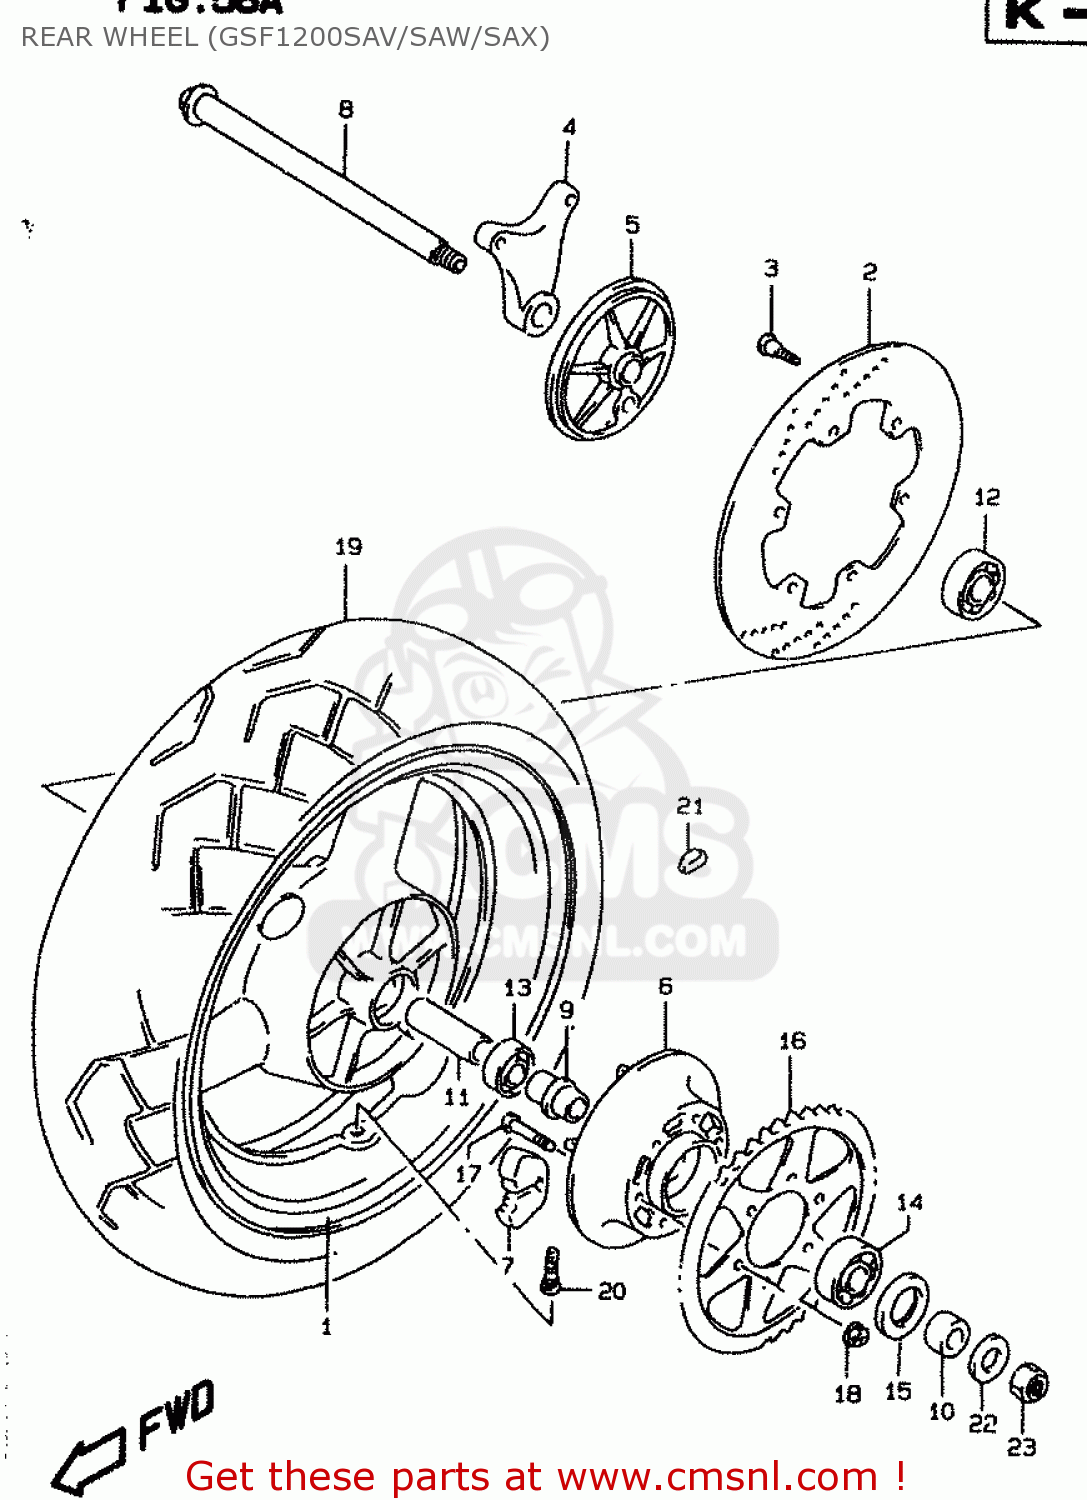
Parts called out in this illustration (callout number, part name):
1	WHEEL SET,REAR (17XMT5)
2	DISC,RR BRAKE
3	BOLT 8X33
4	BRACKET,RR CALIPER
5	PANEL,SPEED SENSOR RR
6	DRUM,RR SPROCKET
7	ABSORBER,RR HUB SHOCK
8	AXLE,RR
9	RETAINER,RR HUB BEARING
10	SPACER,RR AXLE,L
11	SPACER,RR WHEEL HUB BEARING
12	BEARING(20X47X14)
13	BEARING(20X47X14)
14	BEARING(25X62X17)
15	SEAL,OIL(35X62X8)
16	SPROCKET,RR(NT:45-530)
17	BOLT
18	NUT
19	TIRE,RR(180/55 ZR17 73W)
20	VALVE ASSY,WHEEL RIM(TR412)
21	BALANCER,WHEEL (10G)
22	WASHER(18.5X28X2.6)
23	NUT
